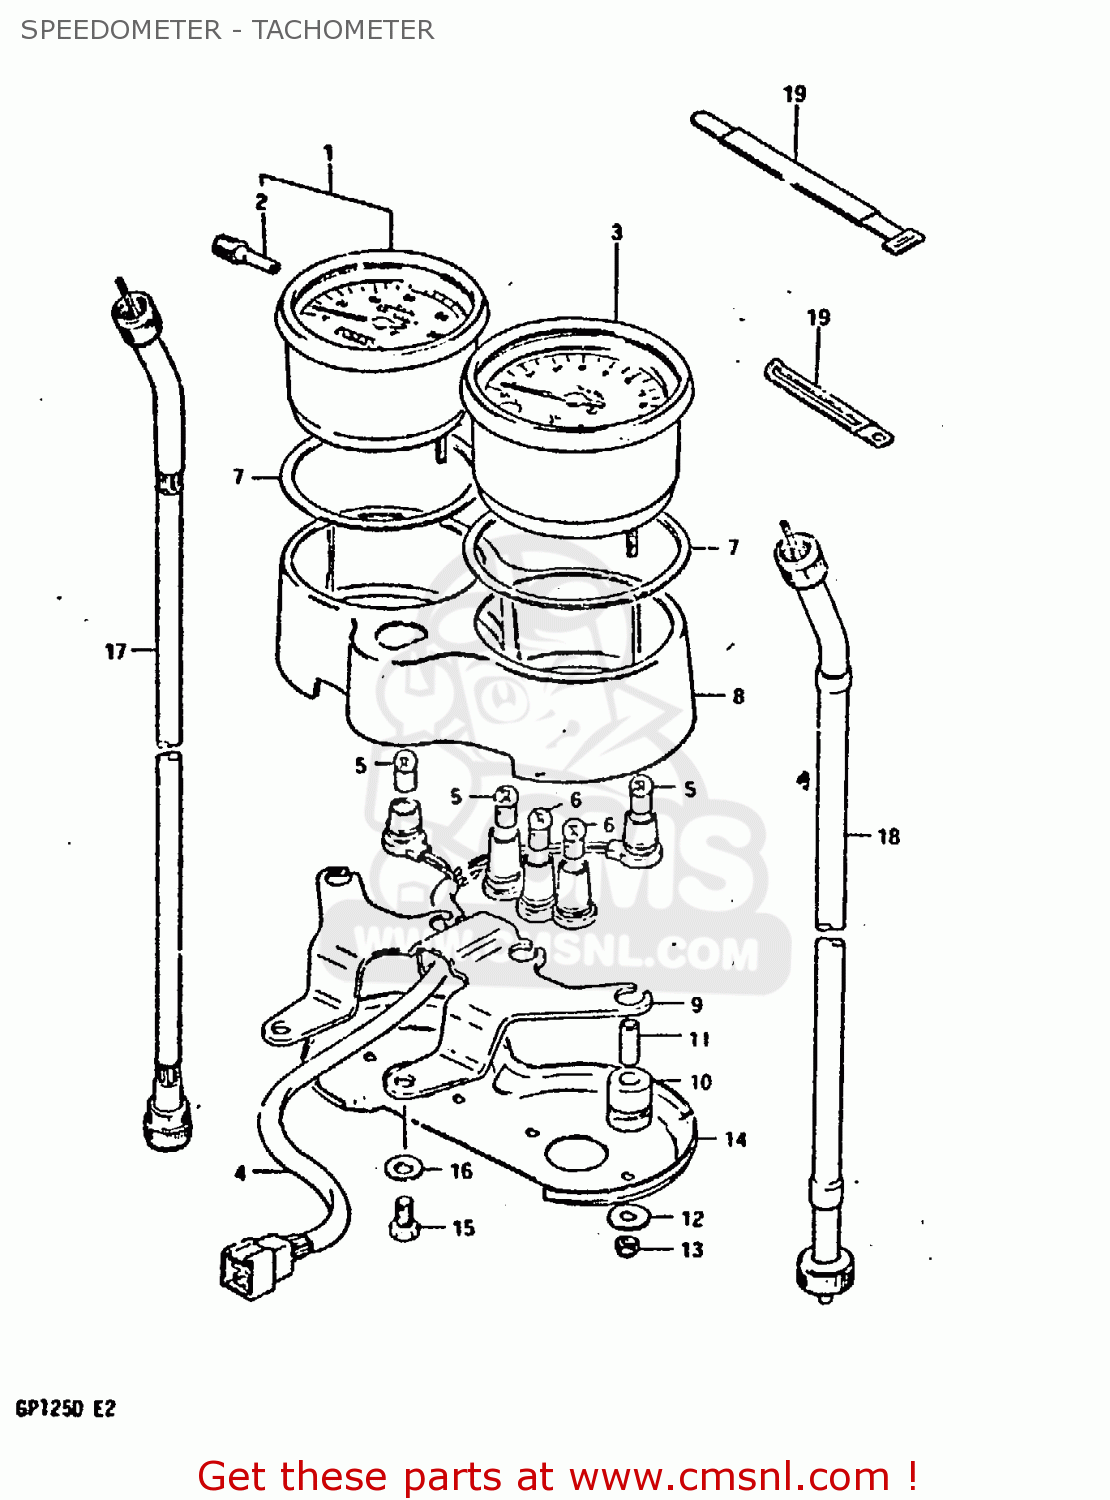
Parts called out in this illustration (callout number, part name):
1	SPEEDOMETER (MILE/KILO)
2	KNOB,TRIP METER
3	TACHOMETER
4	SOCKET
5	BULB(6V1.7W,STANLEY,A61A)
6	BULB(6V/3W)
7	GASKET, METER
8	CASE, METER
9	BRACKET
10	CUSHION
11	SPACER
12	WASHER,METER
13	NUT
14	UNDER PLATE
15	BOLT 8X12
16	WASHER
17	CABLE, SPEEDOMETER
18	CABLE ASSY,TACHOMETER
19	CLAMP
20	CLAMP L:110
